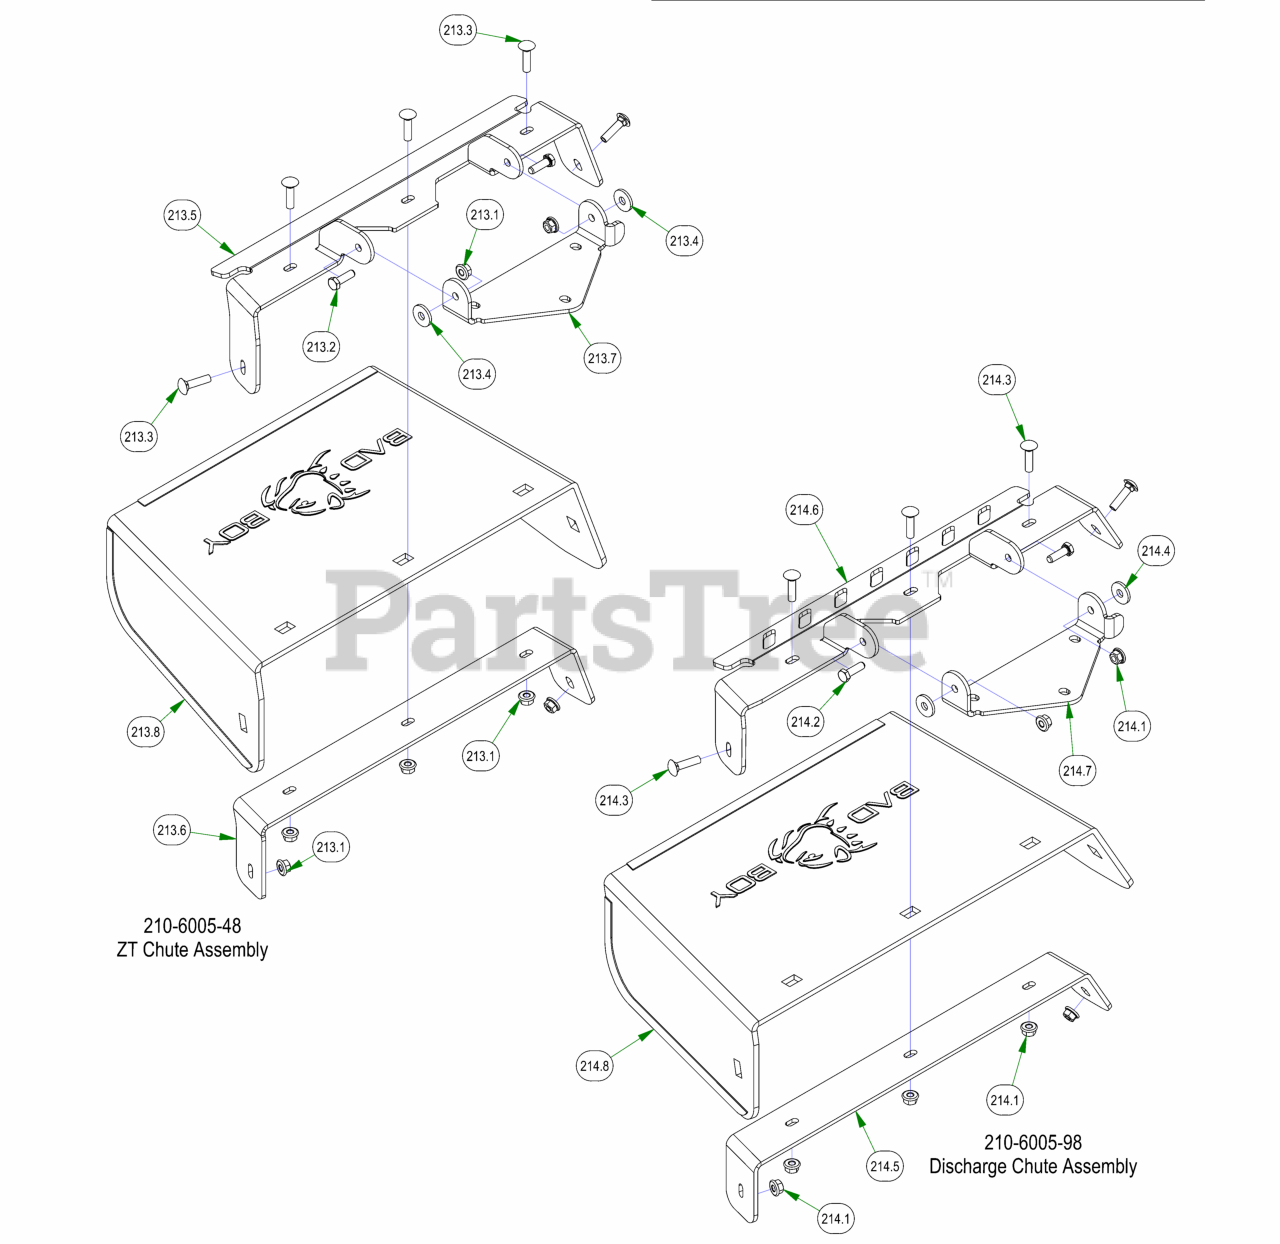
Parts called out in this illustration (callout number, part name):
213	ZT Chute Assembly
213.1	5/16-18 NYLON INSERT FLANGE LOCKNUT ZINC
213.2	5/16-18 X 1 HEX CAP SCREW (GR.5) ZINC
213.3	5/16-18 X 1-1/4 CARRIAGE BOLT ZINC
213.4	.360 ID X .983 OD X .120 THICK FLAT WASHER NYLON
213.5	Discharge Upper Chute Bracket
213.6	Discharge Lower Chute Bracket
213.7	Discharge Chute Hanger (deck mounted)
213.8	Rubber Discharge Chute
214	Discharge Chute Assembly
214.1	5/16-18 NYLON INSERT FLANGE LOCKNUT ZINC
214.2	5/16-18 X 1 HEX CAP SCREW (GR.5) ZINC
214.3	5/16-18 X 1-1/4 CARRIAGE BOLT ZINC
214.4	.360 ID X .983 OD X .120 THICK FLAT WASHER NYLON
214.5	60" Discharge Lower Bracket
214.6	60" Discharge Chute Upper Hanger
214.7	Discharge Chute Hanger (deck mounted)
214.8	Rubber Discharge Chute
